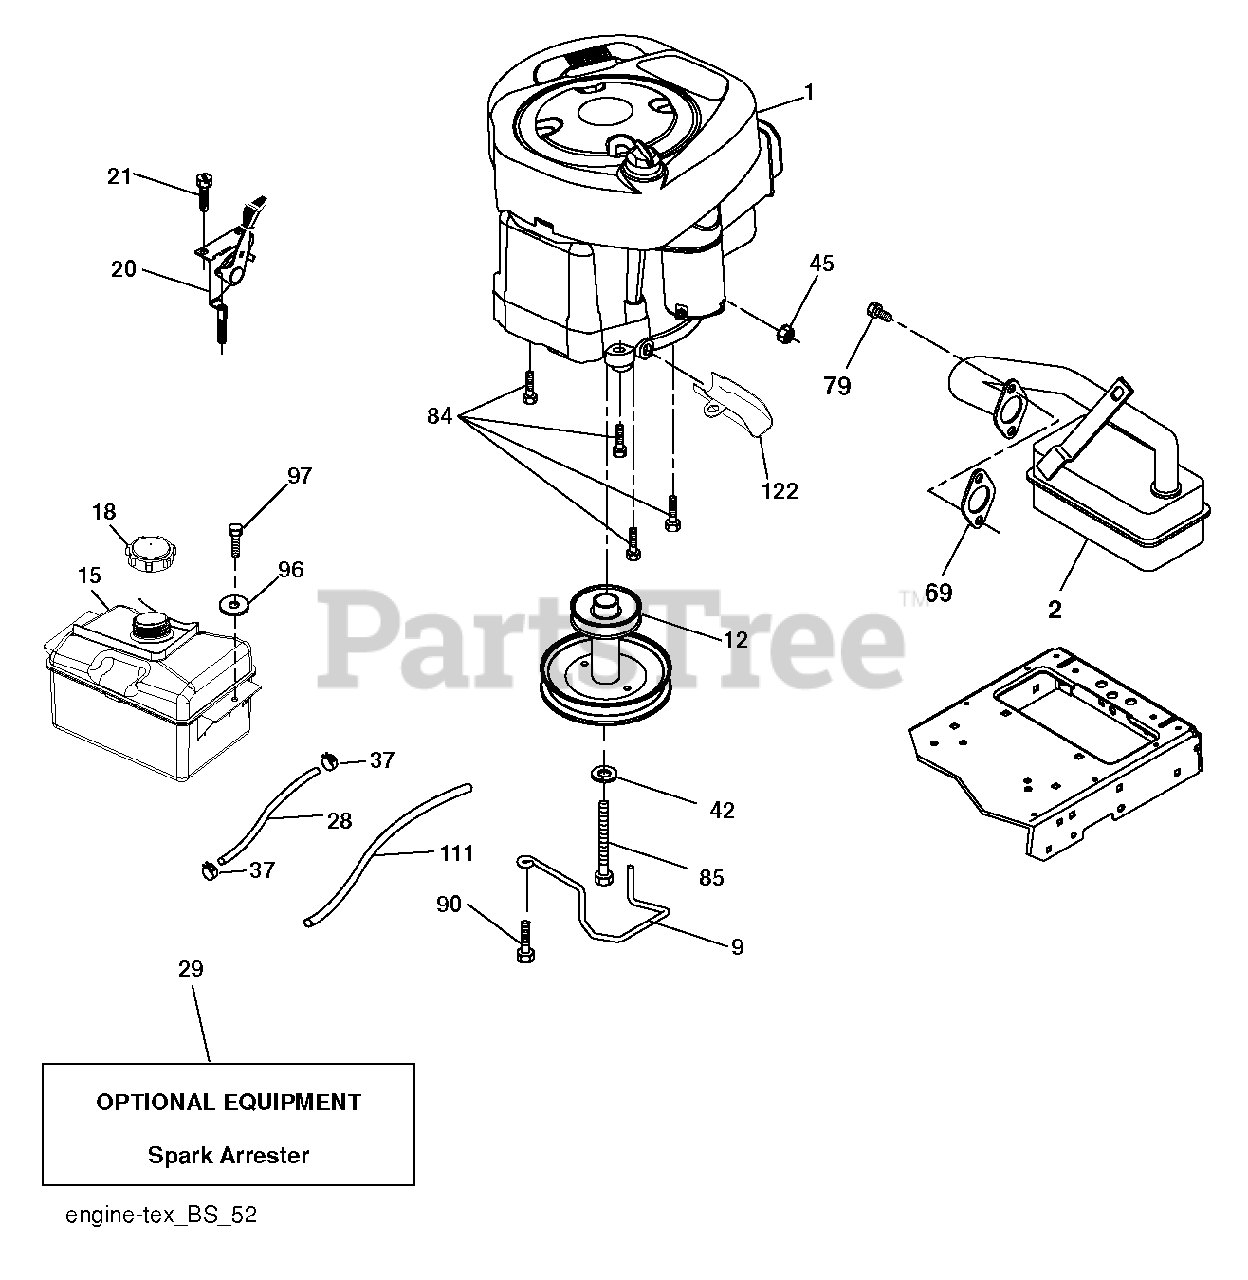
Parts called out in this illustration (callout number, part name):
2	MUFFLER.LT.BRIGGS.14HP.IC/OHV
9	KEEPER.BELT.ENGINE.3.25 (3 2)
12	PULLEY.ENG.CL.MECH.SLVR.LT/YT
15	TANK.ASM.1.5GAL.FRT.W/CAP.EPA
18	CAP.FUEL.2 WAY VENT
20	CONTROL.TH/CK.C.
21	SCREW.#10 X 0.750.BOS
28	LINE.FUEL.20"FRONT.EMI
29	KIT.SPARK ARRESTOR 794945 B&S
37	HOSE CLAMP
42	LOCKWASHER
45	NUT
69	REPL BY 532 27 22-93
79	SCREW.SOCKET HD.5/16-1
84	SCREW.3/8-16
85	BOLT HEX 7/16-20X4-1/4"
90	SCREW 3/8-16X1
97	SCREW HEXWSHR 1/4-20X3/4
111	RP PURGE LINE
122	EXTENSION DRAIN OIL
